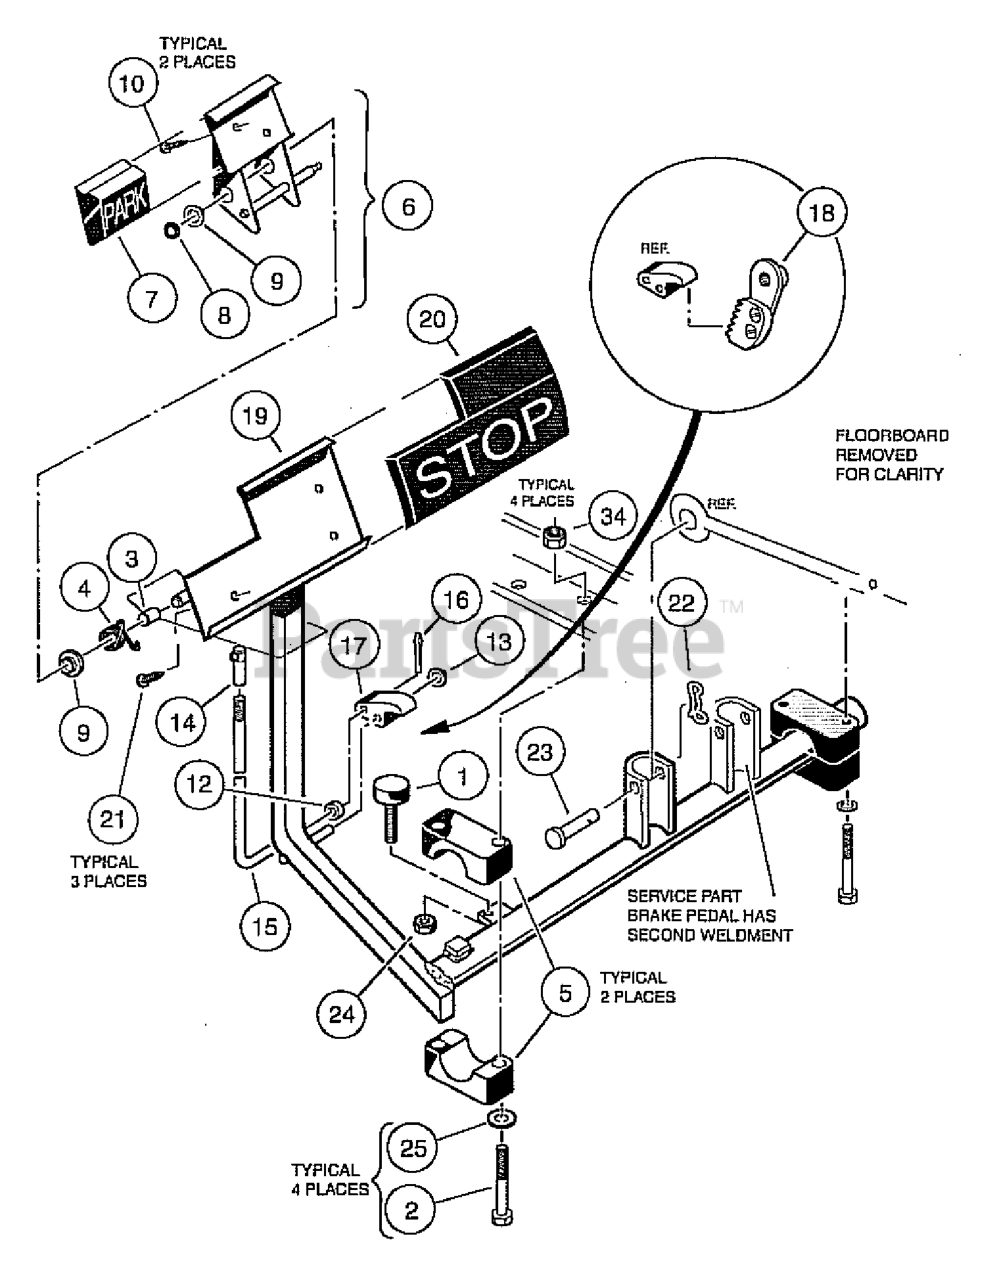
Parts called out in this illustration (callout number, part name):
1	BUMPER, BRAKE PEDAL RUBBER
2	SCREW HEX CAP
3	Hill Brake Spacer
4	SPRING, HILL BRAKE TORSION
5	PACKAGE, BRAKE MOUNTING BLOCK
6	KIT, HILL BRAKE PEDAL
7	PAD, HILL BRAKE
8	PUSHNUT, 3/8
9	BUSHING, NYLON
10	SCREW TYPE AB SHT MTL
11	HILL BRK LATCH KIT 9529&LTR
12	SLEEVE, HILL BRAKE ROD
13	PUSHNUT, 3/8
14	BALL JOINT, 1/4-28
15	Rod, Hlll Brake
16	COTTER PIN 7/64 X 1/2 SS
17	Pawl, Hill Brake
18	Ratchet Assembly
19	BRAKE PEDAL KIT
20	PAD, BRAKE PEDAL
21	SCREW TYPE AB SHT MTL
22	PIN, BOW TIE LOCKING
23	PIN, 3/8 X 1 5/16 CLEVIS
24	NUT, 1/4-20 HEX
25	WASHER, 5/16 TYPE A FLAT
